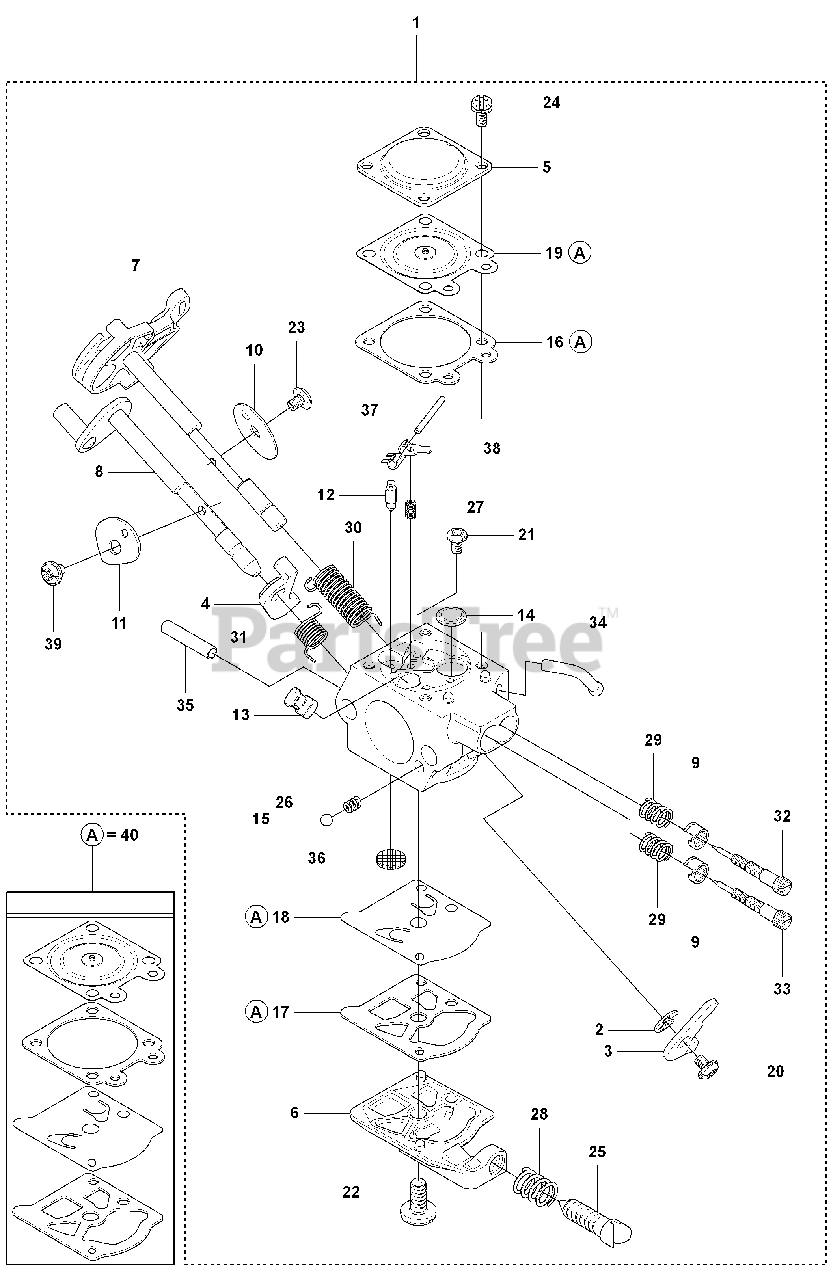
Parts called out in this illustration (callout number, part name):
2	E CLIP
5	THROTTLE SHAFT (W30-832)
9	LIMITER CAP
12	INLET NEEDLE
14	PLUG
18	DIAPHRAGM, FUEL PUMP
19	METERING DIAPHRAGM
23	SCREW
24	RP SCREW W/ WASHER
28	SPRING
36	FUEL INLET SCREEN
37	FULCRUM PIN
